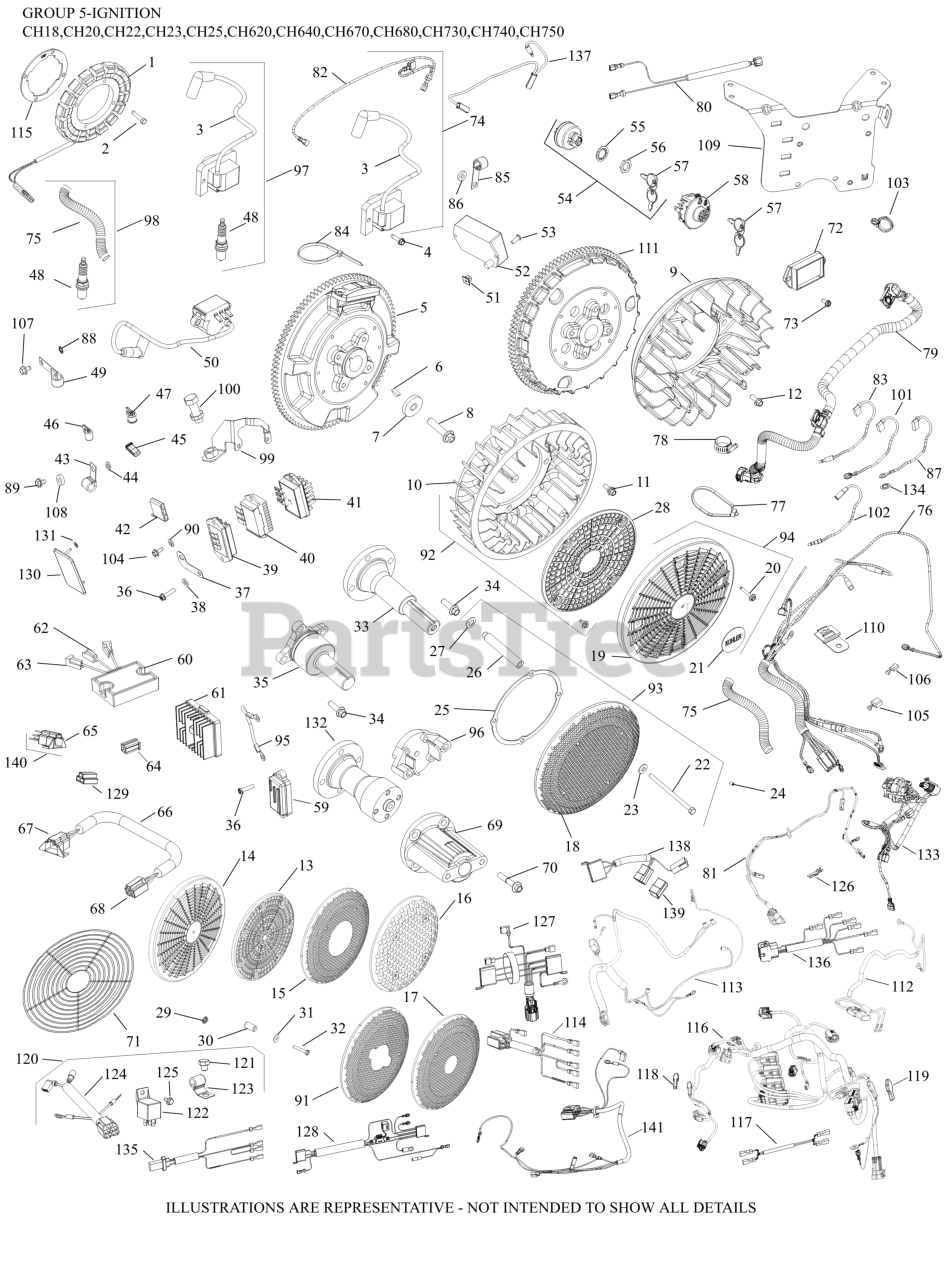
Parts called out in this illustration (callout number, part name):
1	KIT, 15 / 20 AMP STATOR
2	SCREW, THREAD FORMING
3	KIT MODULE IGTN
4	SCREW, THREAD FORMING
6	KEY, 3/16" X 5/8"
7	WASHER, FLAT 13/32"
8	SCREW, FLG M10X1.5X45-USE 25 086 361-S
10	FAN-USE 24 755 253-S
11	BOLT, SHOULDER
20	SCREW, SEMS DOG POINT
28	SCREEN,GRASS LOW PRFLE W/O HOLE
36	SCREW, HEX FLANGE HI-LO
39	REGULATOR/RECT 12/15A HALF-WAVE STD
42	CONNECTOR
43	CLIP, CABLE
48	PLUG, SPARK (STD)
54	SWITCH ASSY, KEY (KM)-USE 25 099 32-S
57	KEY, SET OF 2
58	KIT, KEY SWITCH (SNAP-IN)
72	TACHOMETER
76	HARNESS, WIRING ASSEMBLY
82	LEAD, DUPLEX
83	LEAD, OIL SENTRY
87	LEAD, 20/25 AMP B+
90	WASHER, LOCK
